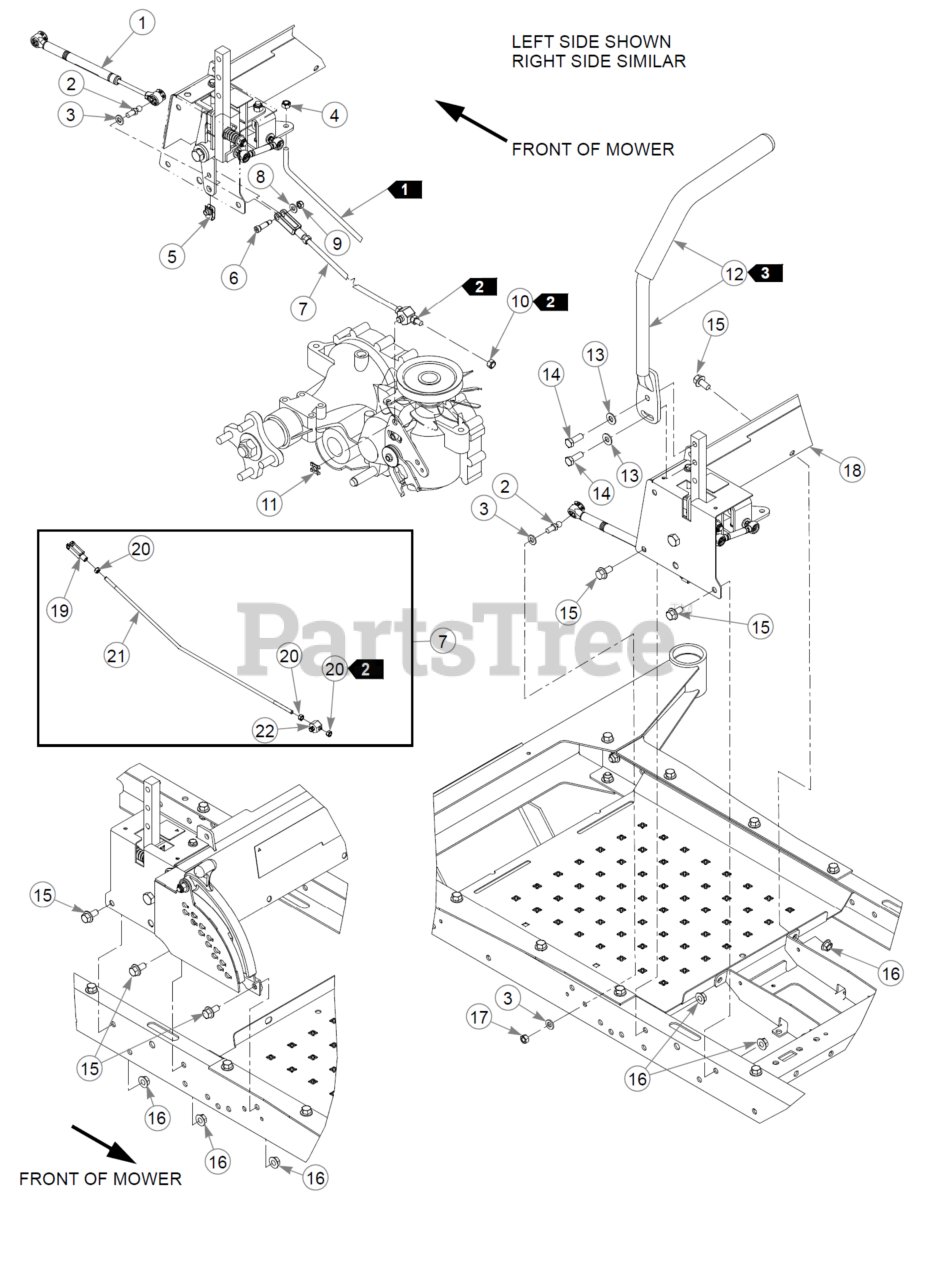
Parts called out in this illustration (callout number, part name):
2	BALL STUD
3	FW 0.343SAE
4	NT .312-18NLG5
5	CN .312-18x.200 MAX THK
6	SB0.312X0.750SH0.250-20
7	STEERING ROD S/A
8	FW 0.281SAE
9	NT .250-20 HXZY NL
10	NT 0.312-24 NL G8
11	CLIP, SAFETY
12	STEERING BAR W/ GRIP
13	FW 0.379X.82X.06 HD ZN
14	CS .375-16X1.00 HX G5 ZN
15	CS .375-16X0.75 HXF G5ZN
16	NT .375-16 FLKG5
17	NT .312-18HXG5
18	STEERING COVER ASSEMBLY
19	YOKE, 5/16-24
20	NT 0.312-24 HX G8
21	ROD, STEERING
22	BLOCK, STEERING CONTROL
